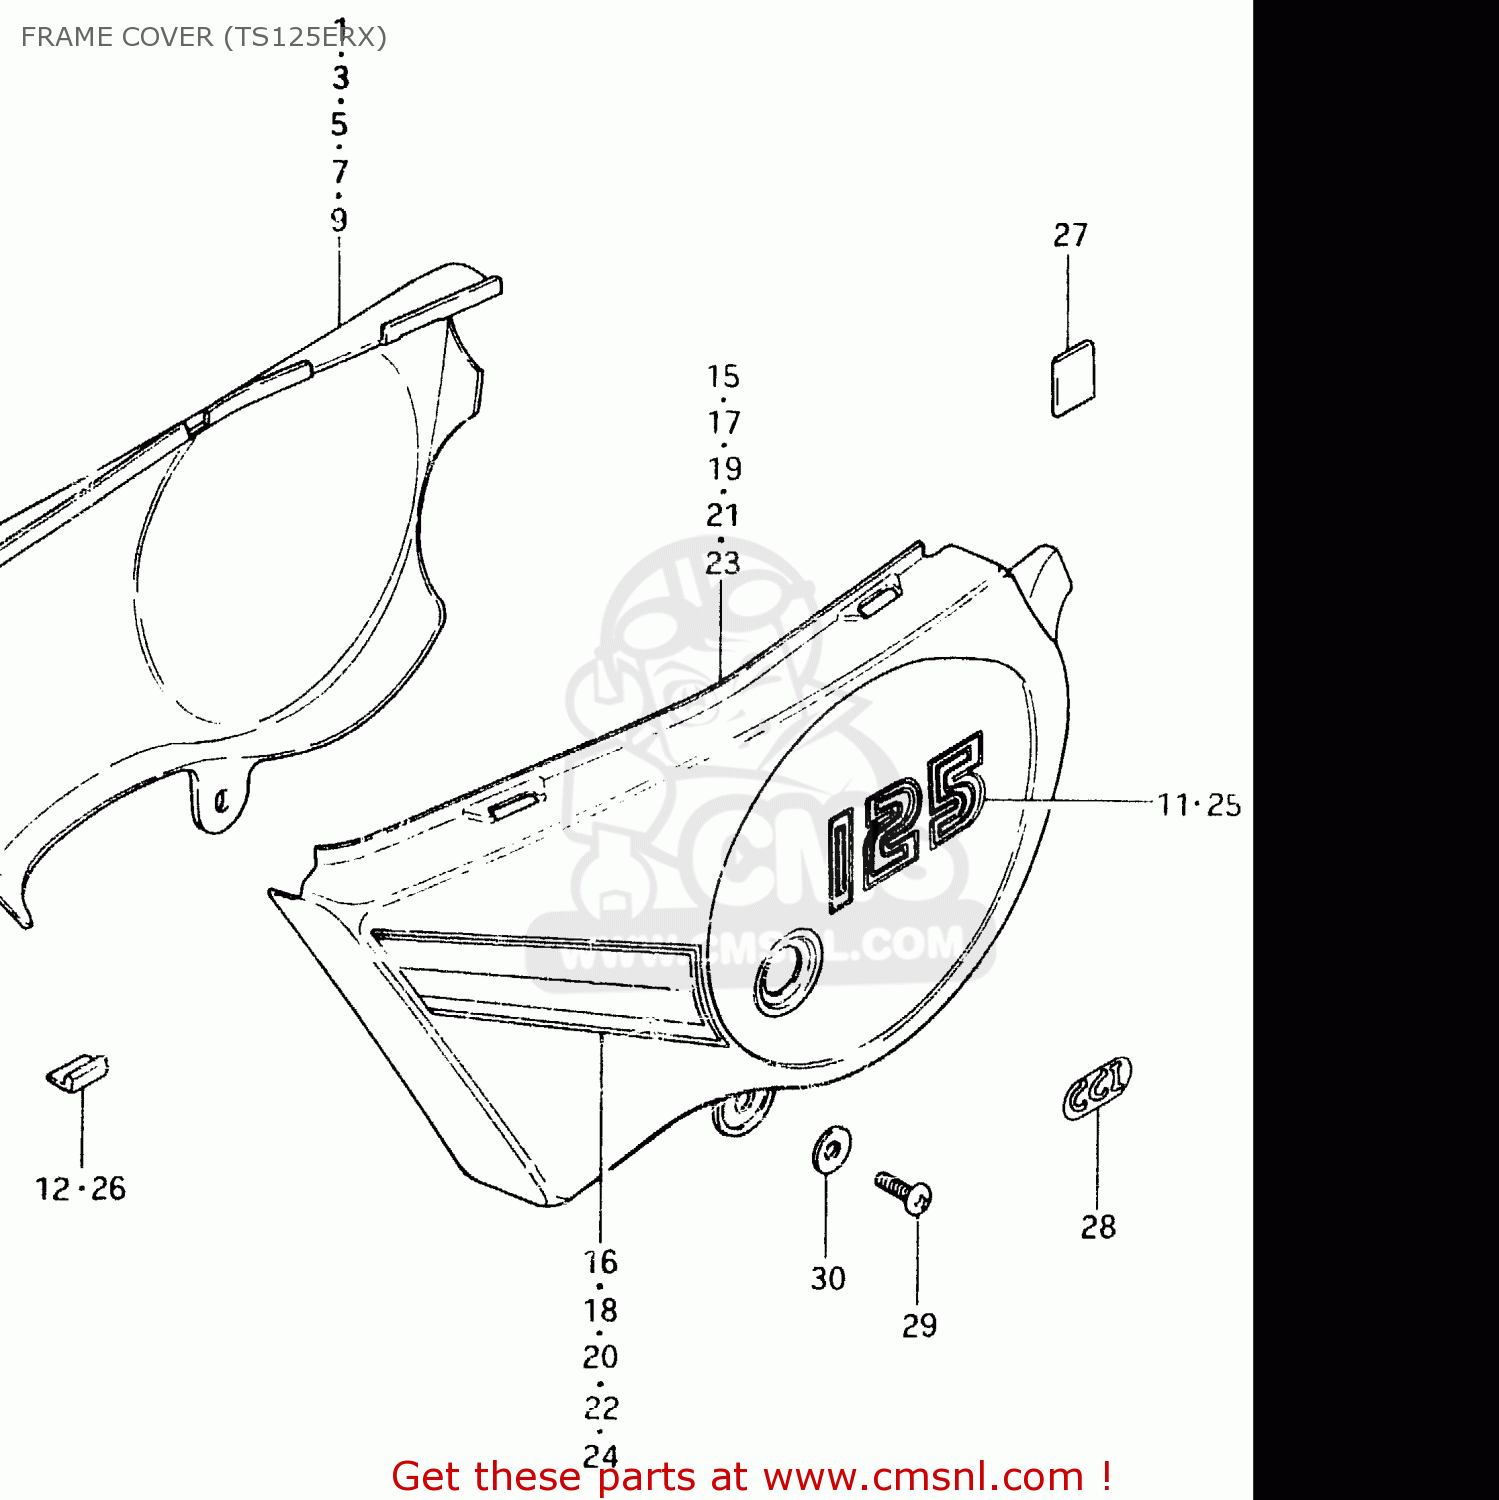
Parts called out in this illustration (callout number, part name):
1	COVER, FRAME RH (RED)
2	TAPE, RH
3	COVER,FRAME,RIGHT
4	TAPE, RH
5	COVER, FRAME RH (WHITE)
6	TAPE, RH
7	COVER, FRAME RH (YELLOW)
8	TAPE, RH
9	COVER,FRAME,RIGHT
10	TAPE, RH
11	EMBLEM, "125" RH (WHITE)
12	CUSHION,FRAME COVER
13	CUSHION,FRAME COVER
14	CUSHION,FRAME COVER
15	COVER, FRAME LH (RED)
16	TAPE, LH
17	COVER,FRAME,LEFT
18	TAPE, LH
19	COVER, FRAME LH (WHITE)
20	TAPE, LH
21	COVER, FRAME LH (YELLOW)
22	TAPE, LH
23	COVER,FRAME,LEFT
24	TAPE, LH
25	EMBLEM, "125" LH (WHITE)
26	CUSHION,FRAME COVER
27	PROTECTOR(170X95X3.0)
28	EMBLEM,CCIS
29	SCREW
30	WASHER
